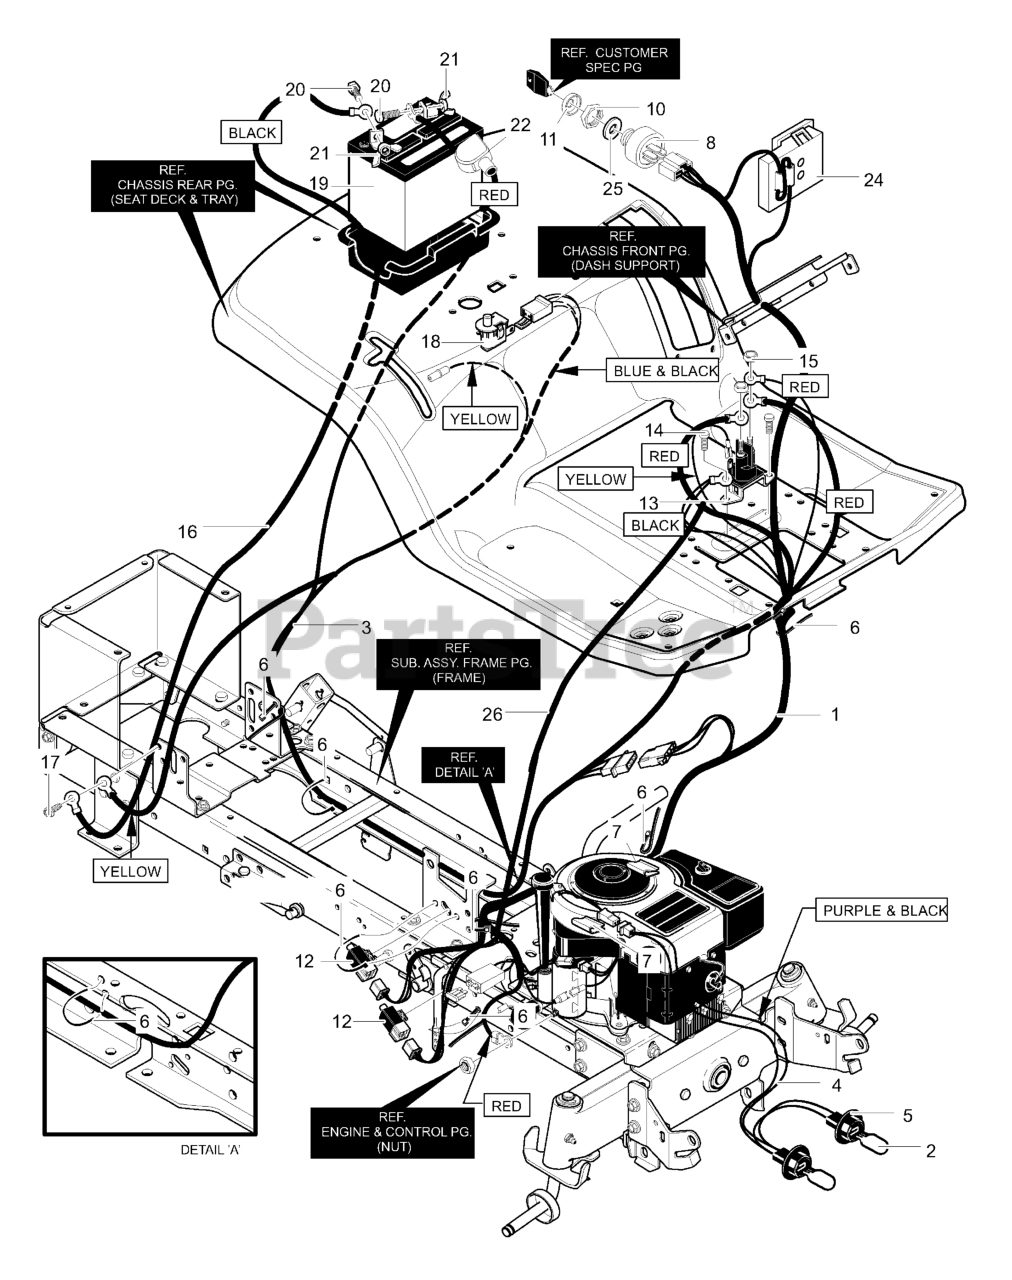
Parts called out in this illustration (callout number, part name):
1	HARNESS
2	BULB, LIGHT
3	WIRE HARNESS, REAR
4	WIRE HARNESS, HEADLIGHTS
5	SOCKET, LAMP
6	TIE, CABLE
7	WIRE CLIP, ADHESIVE
8	SWITCH, IGNITION
10	NUT, IGNITION SWITCH
11	CAP, IGNITION SWITCH
12	SWITCH LIMIT
13	SOLENOID
15	NUT, 1/4-20
16	WIRE, GROUND
18	SWITCH, SEAT
19	BATTERY
20	BOLT
21	NUT, WING
22	BOOT, BATTERY
24	AMMETER
25	WASHER
26	WIRE, LEAD SOLENOID
